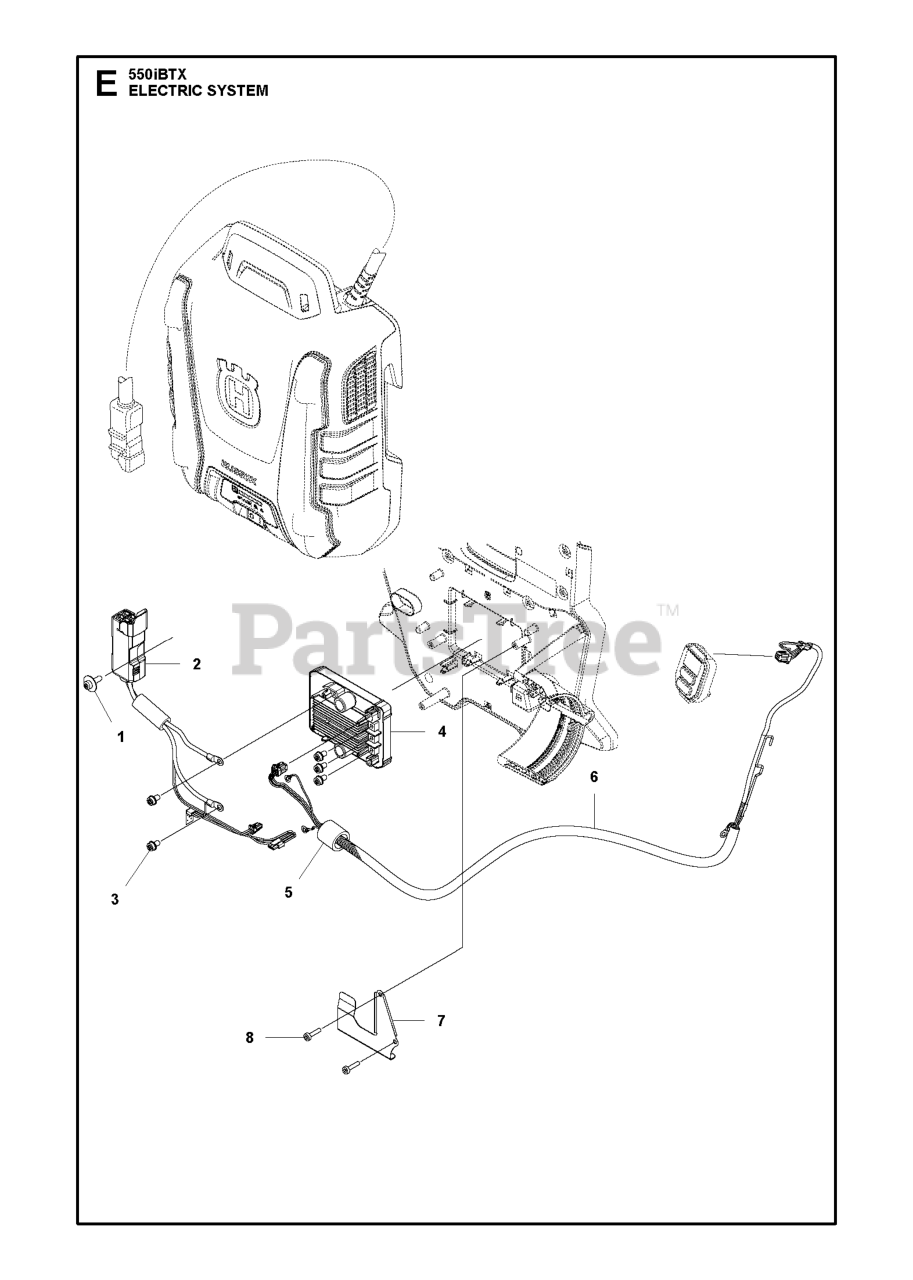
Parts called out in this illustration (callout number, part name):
1	SCREW ITXSCT MT5X16 10.9 TBO
2	WIRING ASSY POWER BLOWER
3	SCREW ITXSCFM M5X8 T27 10.9 Z
4	.ONTROL UNIT G4.A DIGITAL BLOW
5	FERRITE CORE
6	WIRING ASSY SIGNAL BLOWER 550I
7	SPRING PLATE ESD CONTROL UNIT
8	SCREW ITXSCT PW4.2X18 10.9 ZN
